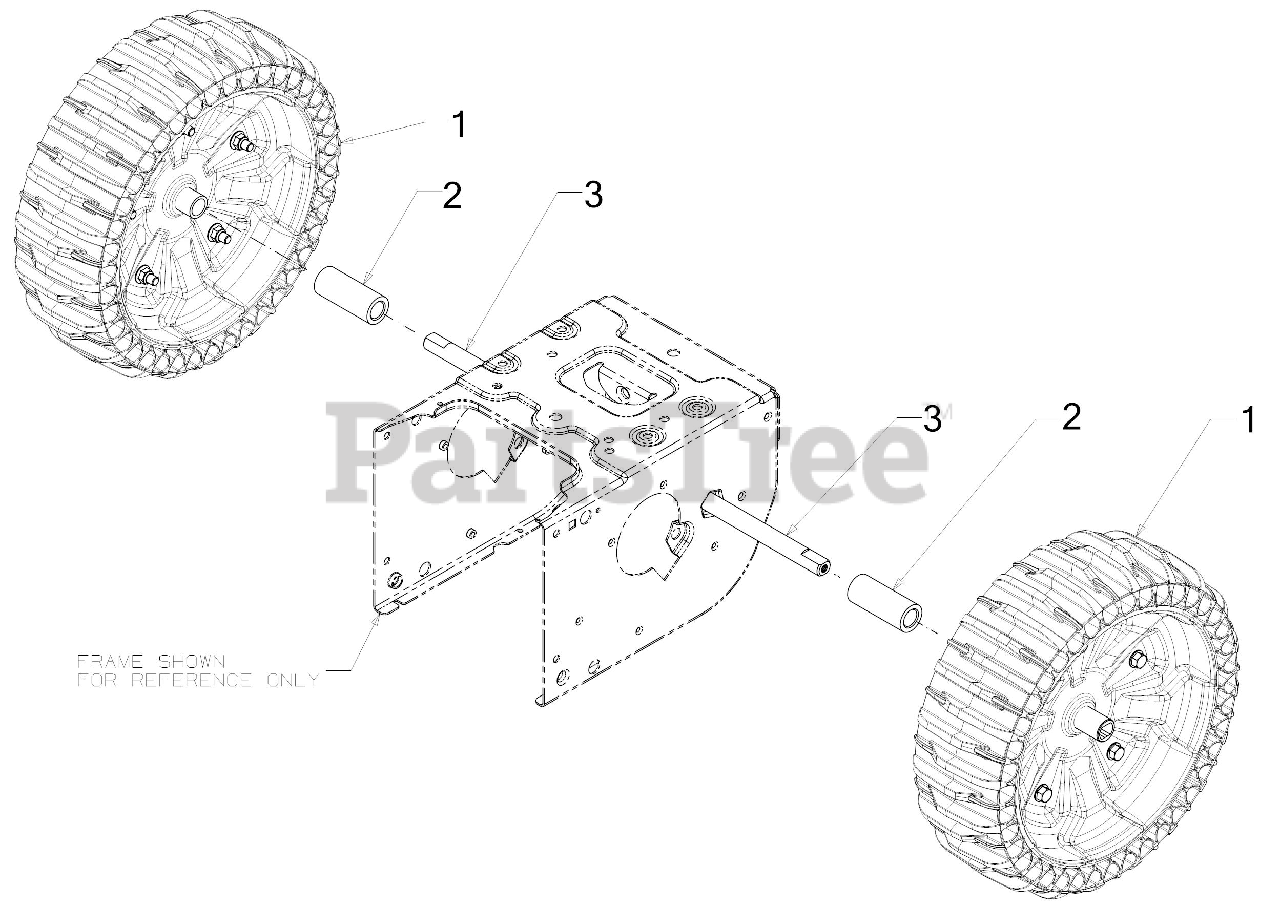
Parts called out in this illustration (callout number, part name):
1	AIRLESS WHEEL
2	WHEEL SPACER 1.25ODX.75X3.00
3	AXLE .75OD x 11.12LG
